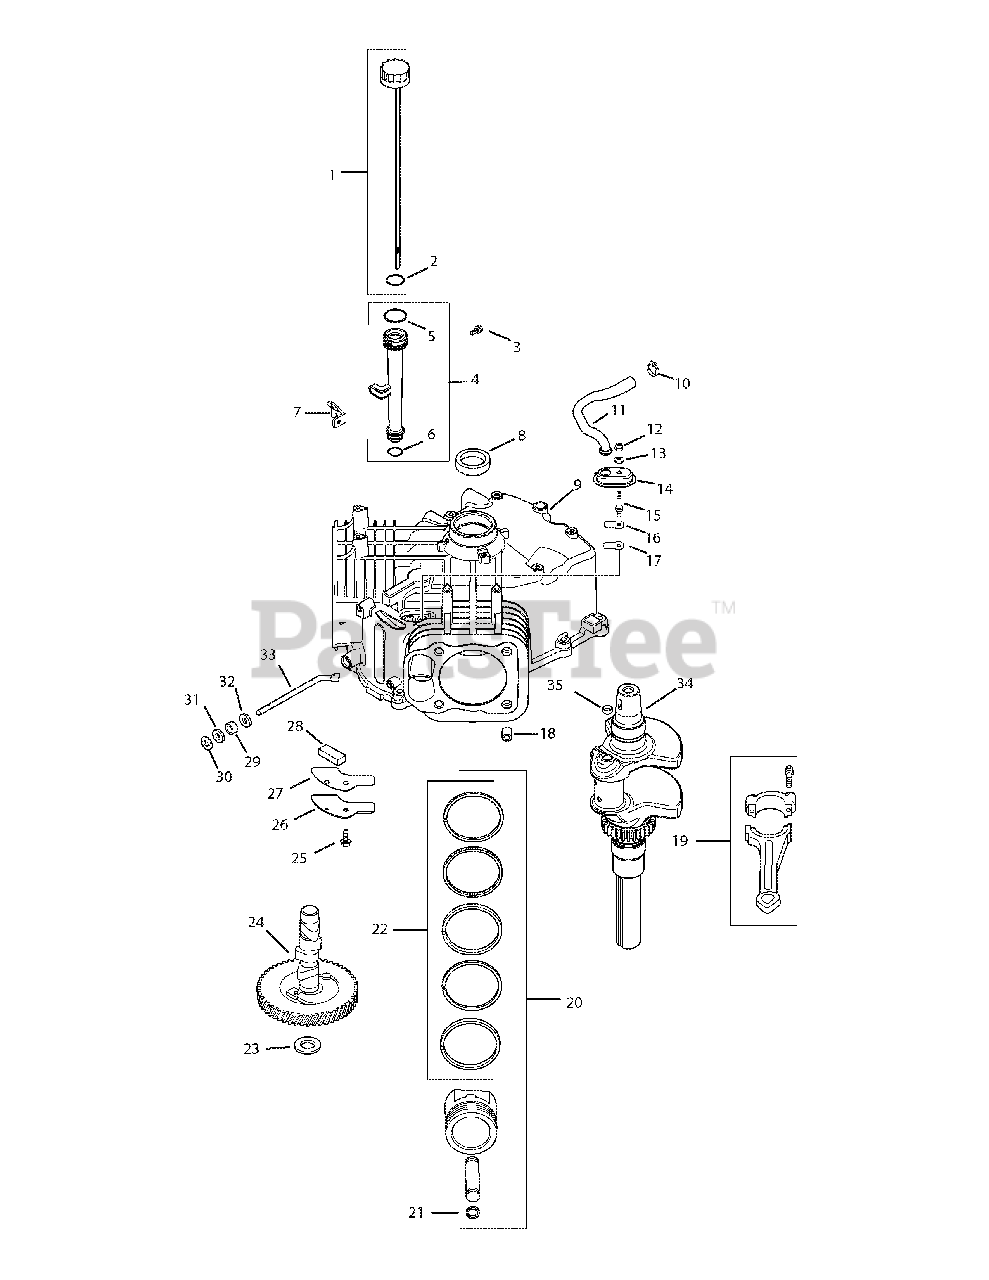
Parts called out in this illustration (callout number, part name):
1	Kit, dipstick
3	Screw, hex. flange M5x0.8x16
4	Tube, oil fill
5	O-Ring, upper oil fill tube
6	O-Ring, lower oil fill tube
7	Bracket, oil fill tube
8	Seal, oil
9	Crankcase
10	Clamp, hose
11	Hose, breather
12	Nut, hex. lock M5x0.8
13	Washer, sealing
14	Housing, breather
15	Stud, breather cover
16	Retainer, breather reed
17	Reed, breather
18	Pin, locating
19	Connecting Rod (Std.)
20	Piston w/Ring Set (Std.)
20	Piston w/Ring Set (.08)
20	Piston w/Ring Set (.25)
21	Retainer, piston pin
22	Ring Set (Std.)
22	Ring Set (.25)
23	Shim, camshaft (yellow)
23	Shim, camshaft (red)
23	Shim, camshaft (black)
23	Shim, camshaft (white)
23	Shim, camshaft (blue)
23	Shim, camshaft (green)
23	Shim, camshaft (gray)
24	Kit, camshaft
25	Screw, hex. flange M6x1.0x16
26	Cover, breather
27	Gasket, breather cover
28	Filter, breather
29	Seal, governor cross shaft
30	Ring, retainer
31	Washer, plain 8 mm
32	Washer, flat 1/4"
33	Shaft, governor cross
34	Crankshaft
